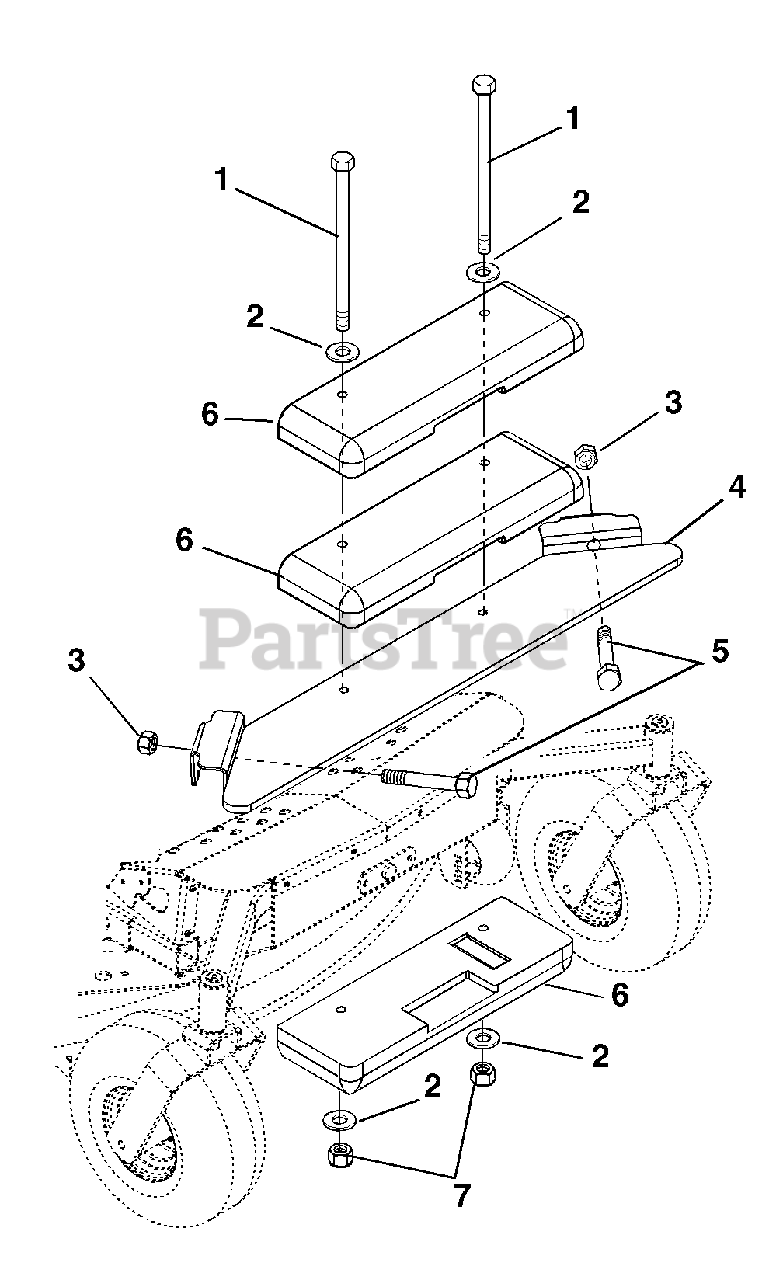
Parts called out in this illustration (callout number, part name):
1	Bolt-Hex .50-13 x 7.50 Grade 5
2	Washer-Flat-Steel .51 x 1.00 x .062
3	Nut-Locking-Nylon .38-16
4	Weldment-260Z Counter Weight
5	Bolt-Hex .38-16 x 3.00 Grade 5
6	Counterweight
7	Nut-Locking-Center .50-13
